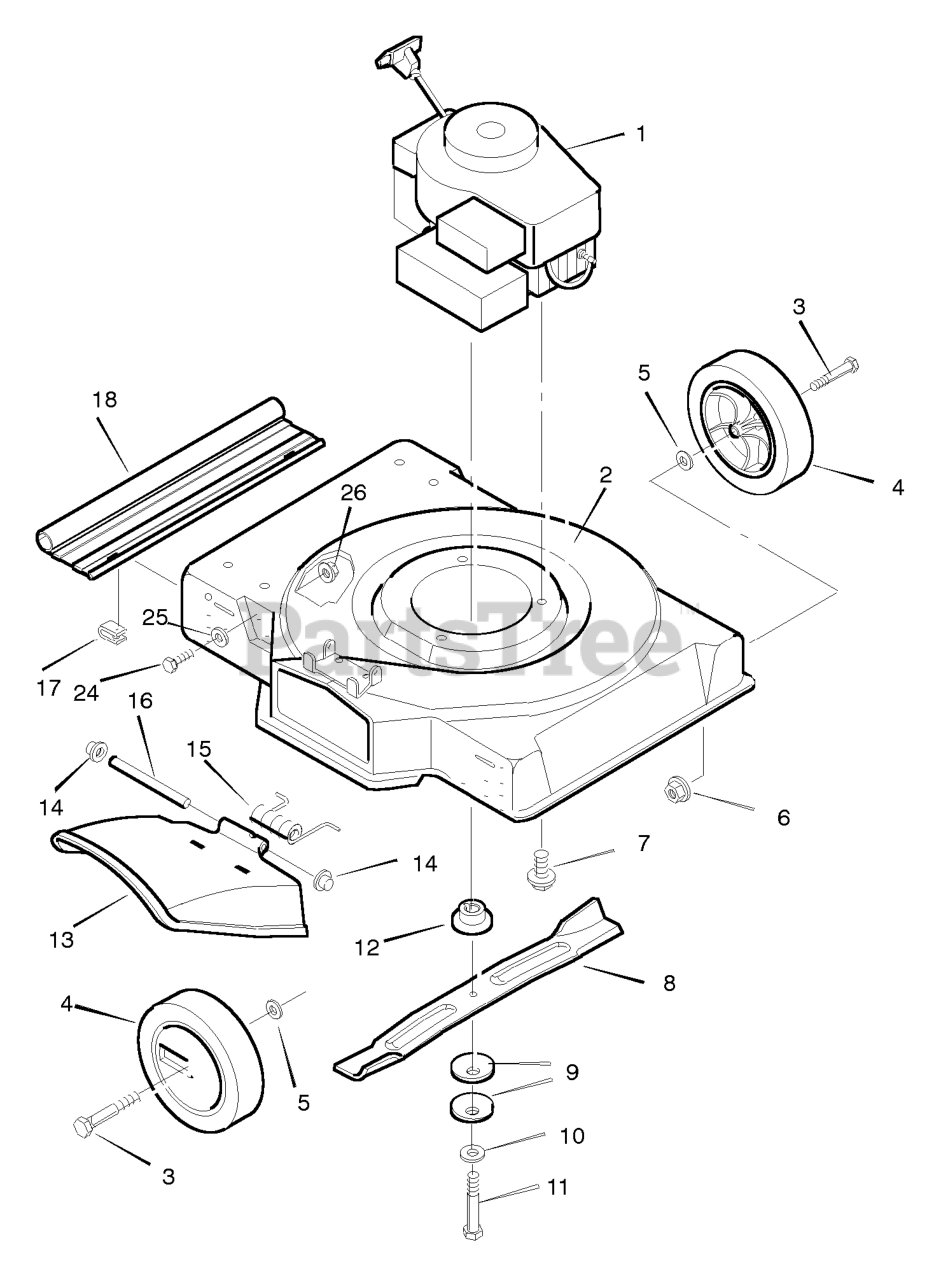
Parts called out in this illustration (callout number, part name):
1	Engine *
2	Housing, For Non-Folding Handle
3	Bolt, Axle
4	Wheel and Tire
6	Locknut, Flange
7	Bolt, Engine
9	Washer, Belleville
11	Bolt, Hex
12	Adapter, Blade
13	Deflector, Chute
14	Push-On Cap
16	Pin, Pivot
17	Retainer
18	Deflector, Rear
24	Bolt, Hex
26	Locknut, Flange
